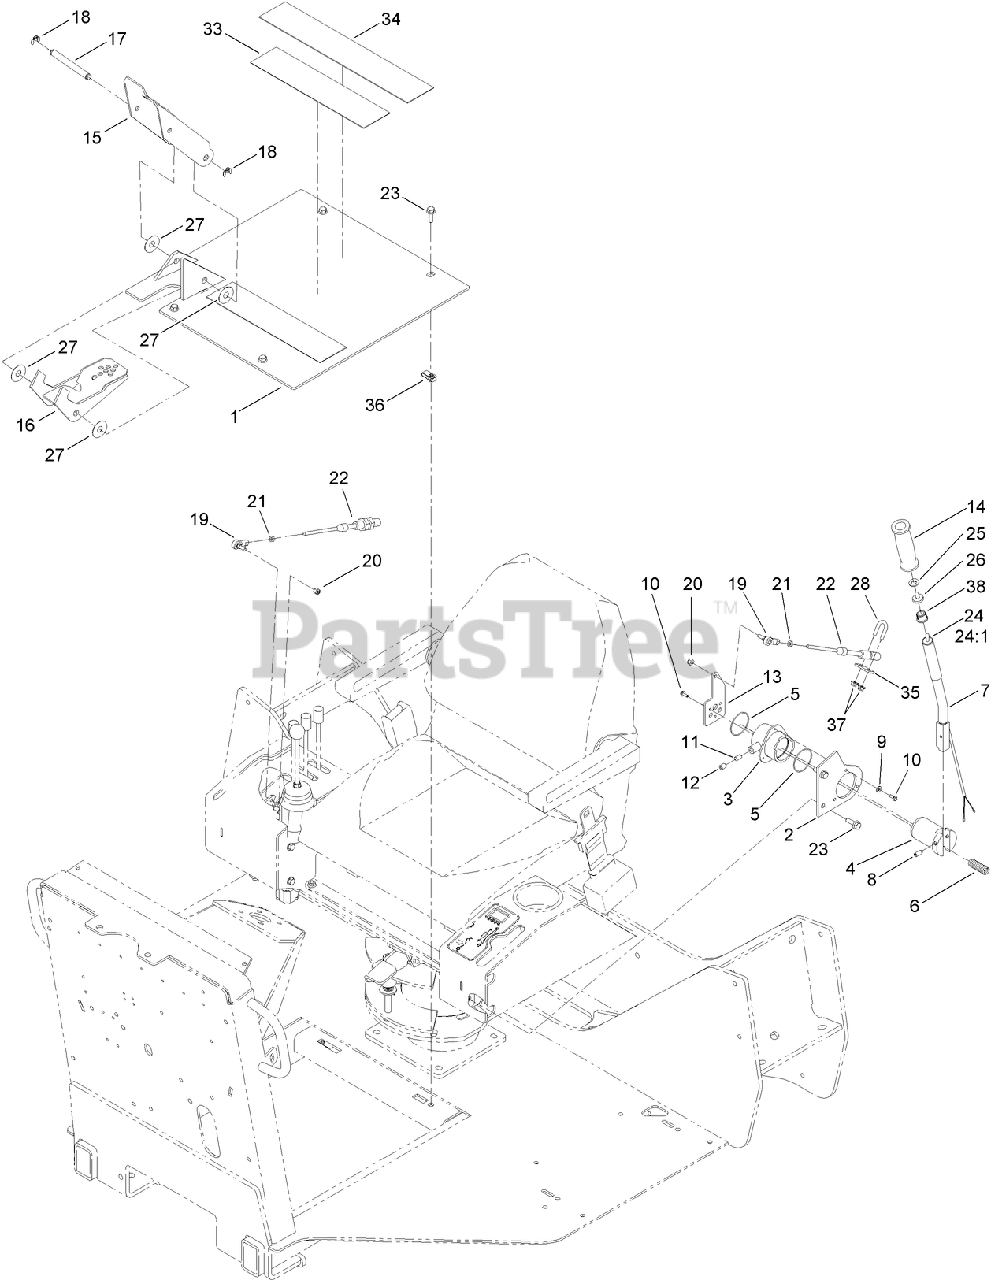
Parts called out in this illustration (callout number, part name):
1	PLATE-FLOOR
2	PLATE-GUSSET
5	O-RING
6	SPRING-Locking
7	HANDLE
8	SCREW-Set
9	WASHER-FLAT
10	SCREW-HWH
11	PLUG-FRICTION
12	SCREW-HSH
13	PLATE-CONTROL
14	GRIP-Handle
15	PEDAL-TOE
16	PEDAL-HEEL
17	PIN-Pedal
18	RING-CLIP, LOCKING
19	ROD END-FEMALE
20	NUT-LOCK
21	NUT-JAM
22	GROUND DRIVE CONTROL CABLE ASM
23	SCREW-HHF
24	ON/OFF TOGGLE SWITCH ASM
24:1	SWITCH-TOGGLE
25	WASHER-FLAT
26	BOOT-SWITCH, TOGGLE
27	WASHER
33	STRIP-ANTI SKID
34	STRIP-ANTI SKID
37	NUT-HF
38	BUSHING
